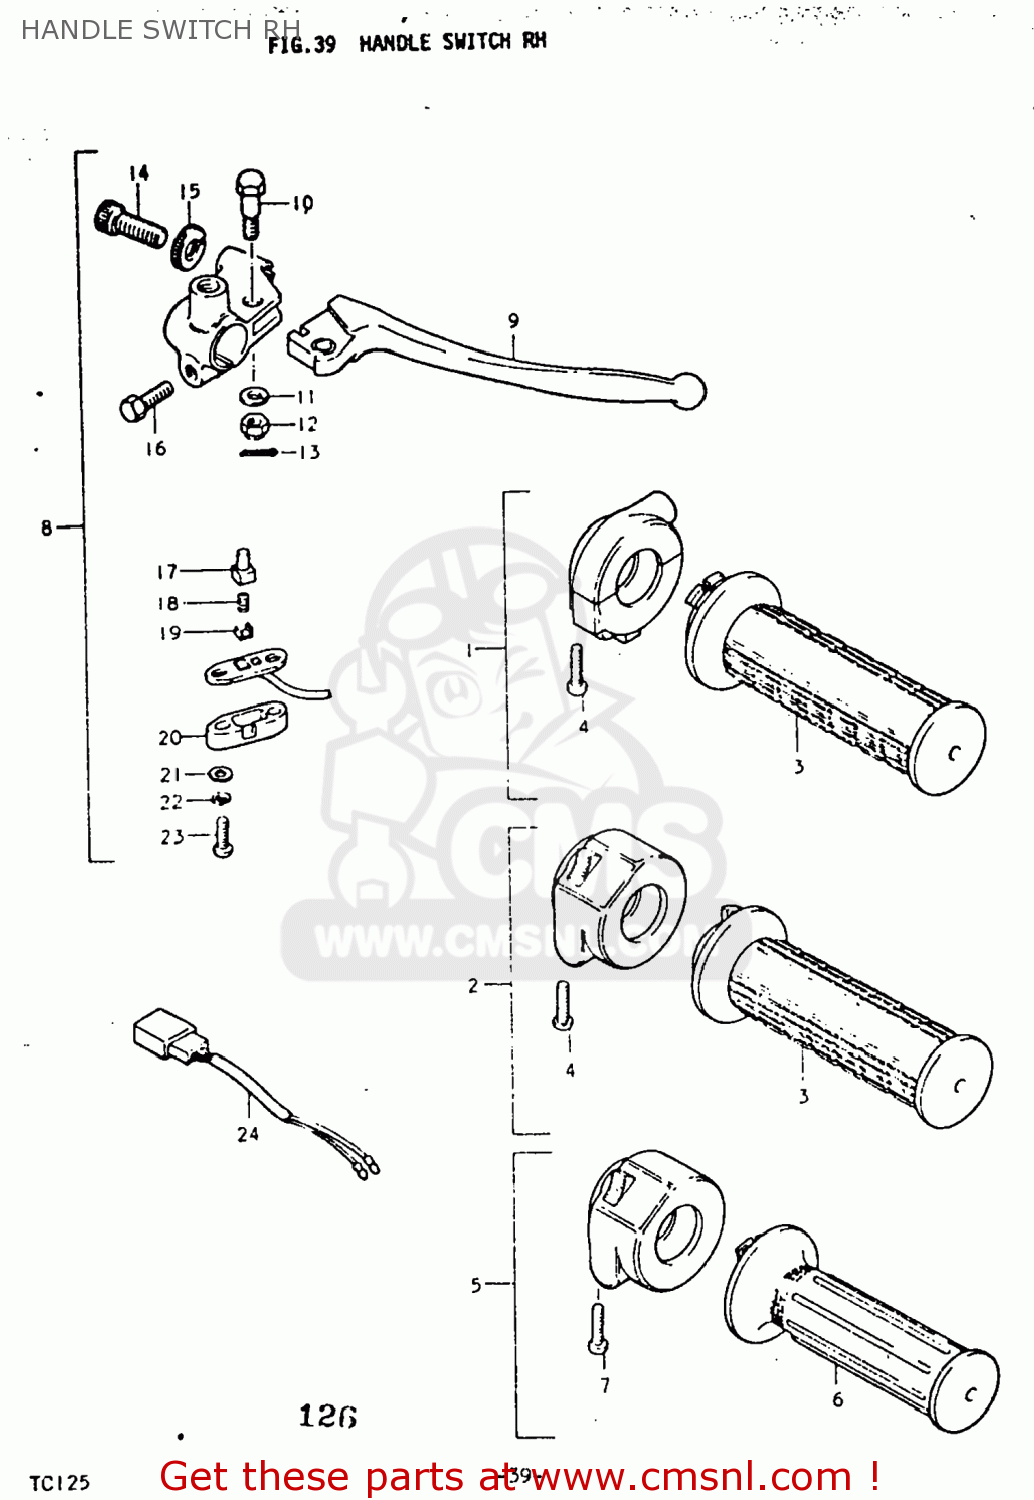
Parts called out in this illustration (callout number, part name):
1	GRIP ASSY,THROTTLE
2	GRIP ASSEMBLY,THROTTLE
3	GRIP,THROTTLE
4	SCREW
5	GRIP ASSEMBLY,THROTTLE
6	GRIP,THROTTLE
7	SCREW
8	LEVER ASSEMBLY,BRAKE
9	LEVER ASSEMBLY,ADJUST
10	BOLT,LEVER
11	LOCK WASHER
12	NUT,LEVER FITTNG
13	COTTER PIN
14	ADJUSTER,CABLE
15	NUT,CABLE ADJUSTER
16	BOLT
17	HOLDER
18	SPRING
19	PLATE
20	COVER,FR BK TERMINAL BASE
21	WASHER
22	LOCK WASHER
23	SCREW
24	LEAD WIRE
